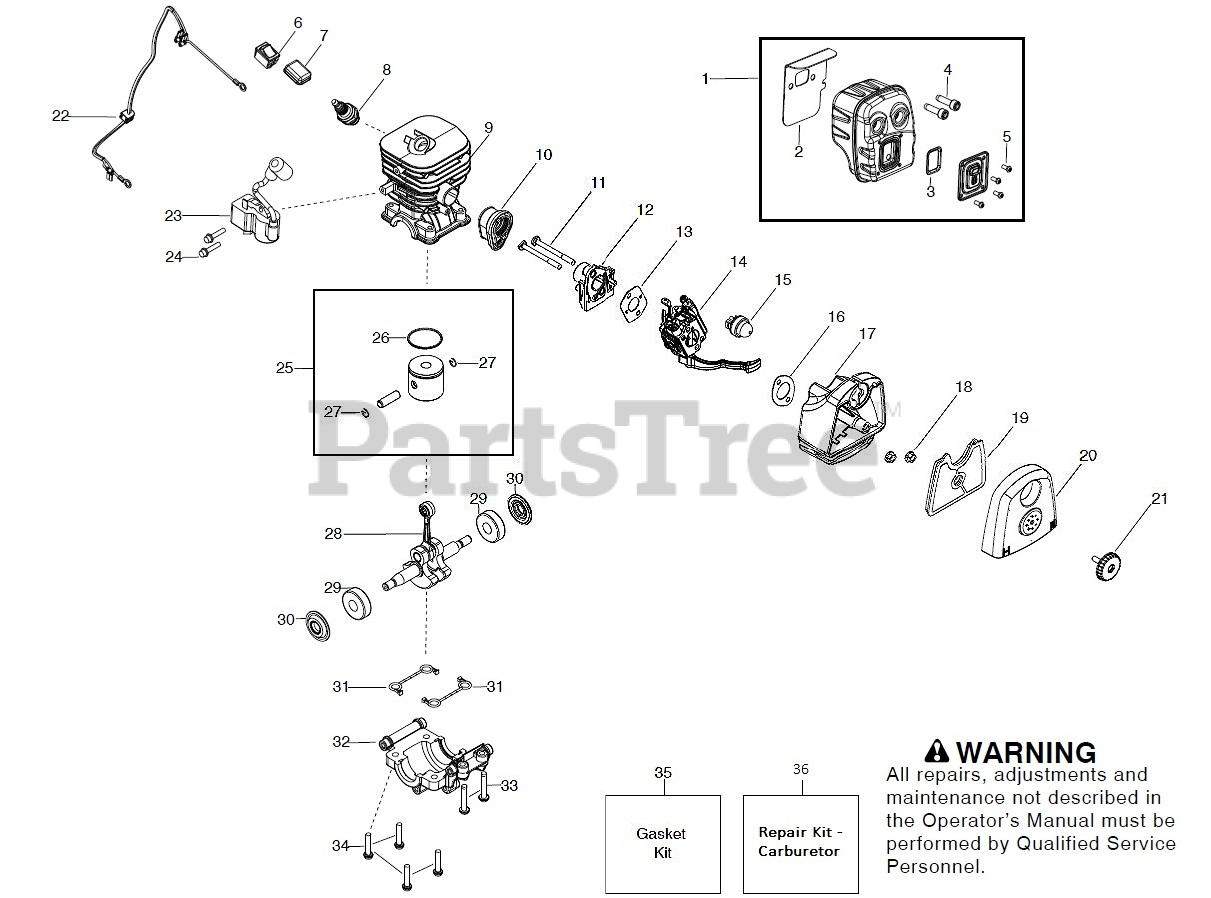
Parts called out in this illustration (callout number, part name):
1	ASSY MUFFLER
3	KIT, SPARK SCREEN
4	BOLT MUFFLER
5	SCREW-6-19X5/16PLAST PA
6	Switches
7	PROTECTOR, SWITCH
8	PLUG SPARK (RCJ6-Y)
9	Cylinder
10	BOOT, CARB
11	SCREW
12	PLATE, CARB
14	KIT CARBURETOR
15	AIR PURGE
17	BASE, AIRBOX
18	NUT
19	Air Filters
20	COVER, AIRBOX
21	KNOB ASSY AIRBOX COVER
22	ASSY, LEADWIRE
23	MODULE IGNITION 125B HAOLONG
24	SCREW M4 X .70 TT 16MM
25	KIT - PISTON
26	RING PISTON
27	WRIST PIN RET.
29	BEARING RADIAL BALL (6201)
30	CRANKSHAFT SEAL
32	CAP - BEARING
33	SCREW
34	SCREW-M5-0.8 X 25MM(TAP)
35	GASKET
36	Gaskets
